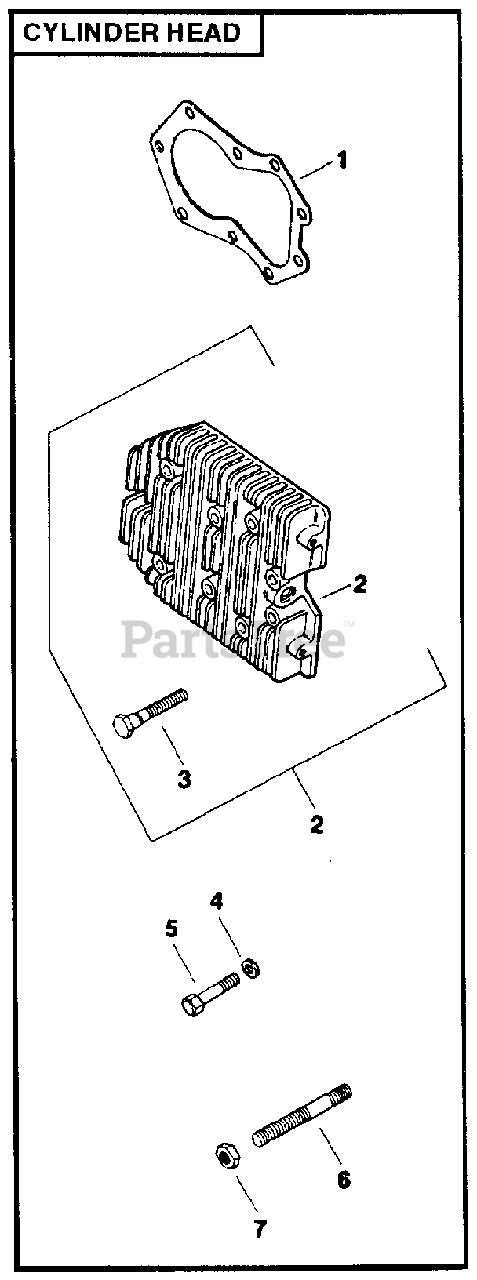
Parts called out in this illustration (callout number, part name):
2	KIT, CYL. HEAD
4	WASHER
7	NUT
